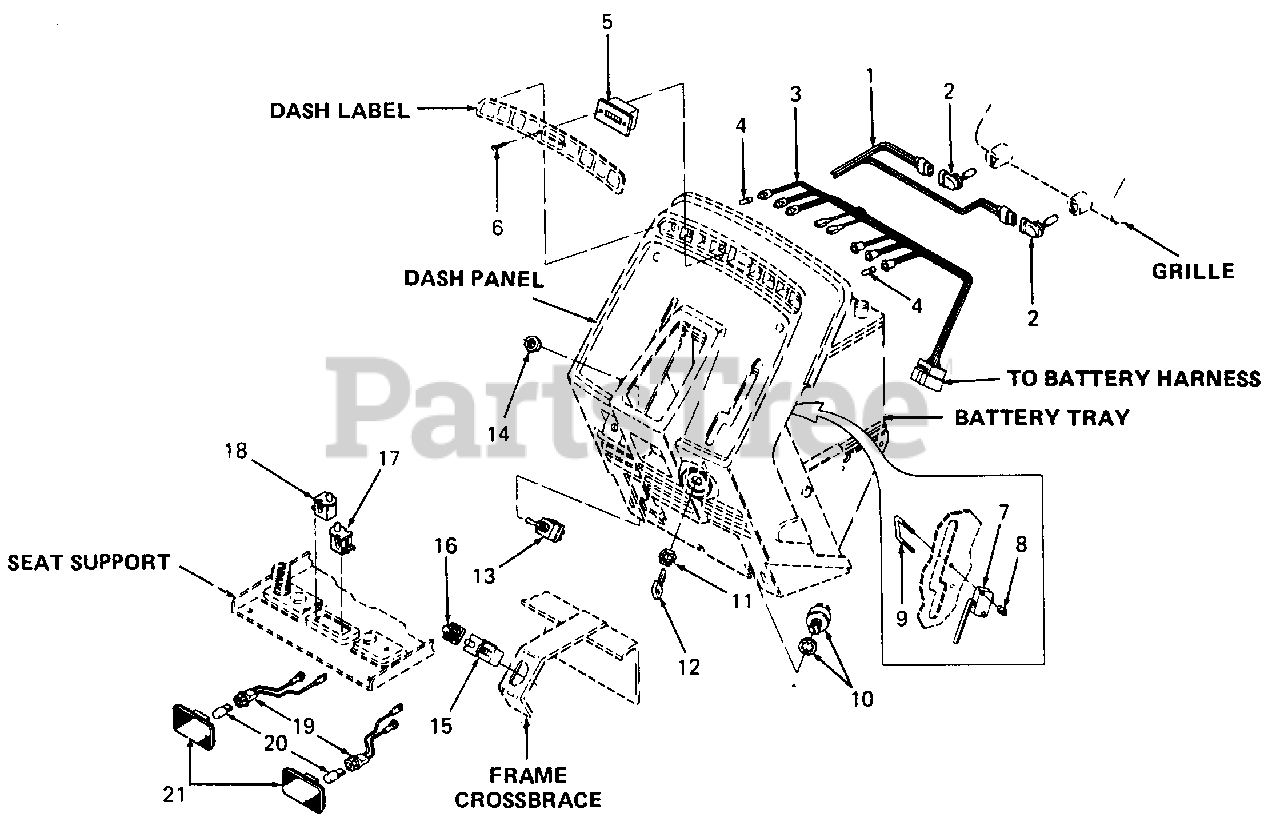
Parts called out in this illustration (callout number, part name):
1	Harness, Main Wire
2	Bulb, Head Lamp
3	Harness, Indicator Wire
4	Bulb, Indicator
5	Hour Meter
6	Screw, Truss Hd Tapp, #6 X .62 Lg
7	Switch, Reverse
8	Nut, Hex Insert Lock, #4-40
9	Screw, Switch
10	Switch, Ignition
11	Nut, Ignition Switch
12	Key, Ignition (Set of 2)
13	Switch, PTO
14	Nut, Hex, 1/2-27 X .100 Thk
15	Switch, Interlock
16	Boot, Switch
17	Switch, Snap Mount Normally Closed (Grey)
18	Switch, Snap Mount Normally Open (Black)
19	Cable Assy, Tail Light
20	Bulb, Tail Light
21	Lens Assy, Tail Light
